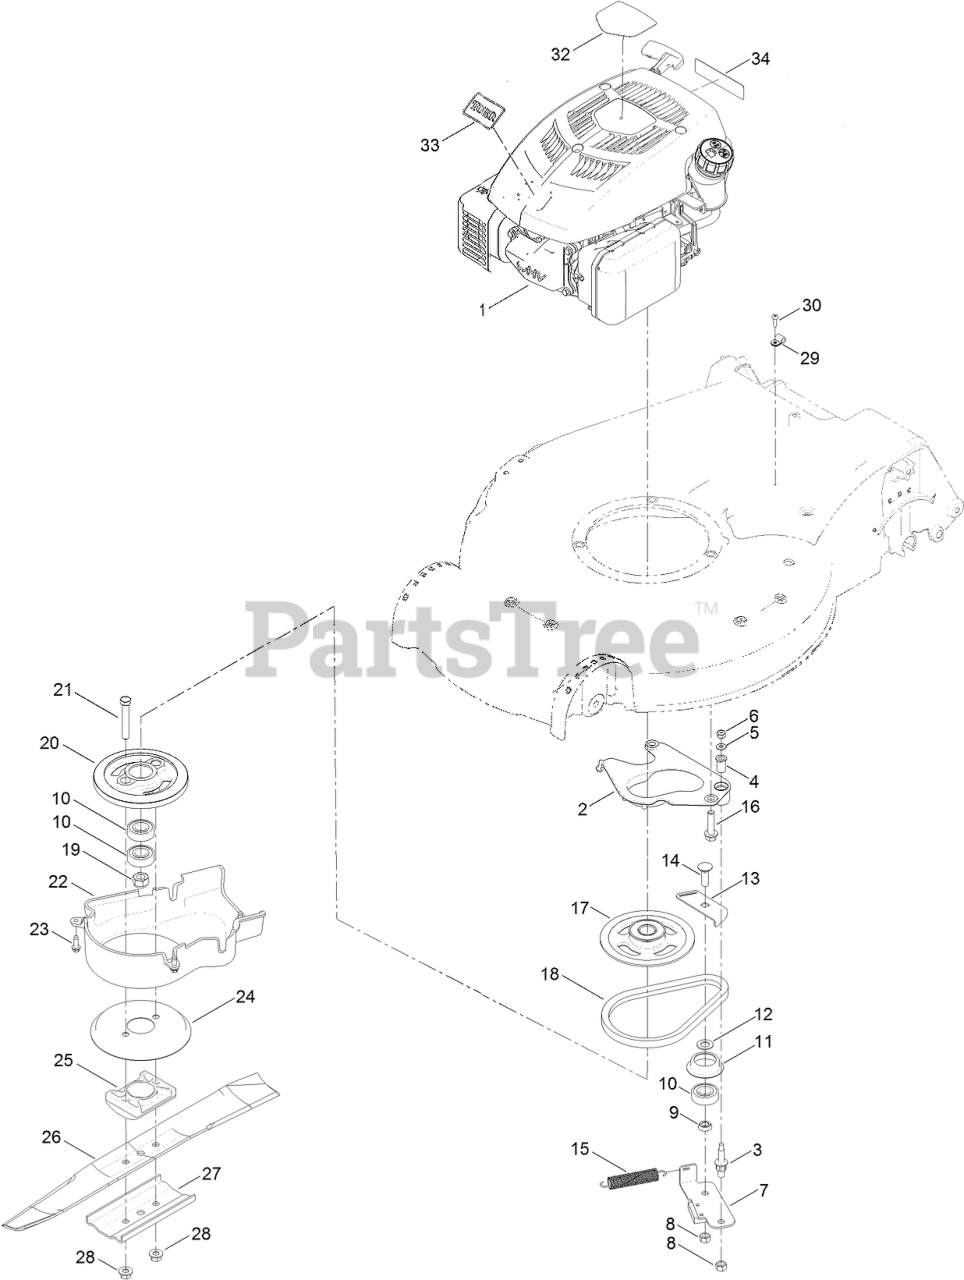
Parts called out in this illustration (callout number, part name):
1	ENGINE-1P65F-2
2	PLATE-ANCHOR
3	BOLT-SHOULDER
4	BUSHING
5	WASHER-FLAT
6	NUT-LOCK, NI
7	PLATE-BRAKE
8	NUT-HEX
9	SPACER-BEARING
10	BEARING-BALL
11	RETAINER-BELT
12	SPACER
13	PLATE-GUIDE
14	BOLT-CARR
15	SPRING-TENSION, BRAKE
16	SCREW-HWH
17	PULLEY
18	BELT
19	NUT-HEX
21	SCREW-HH
23	SCREW-HWHTF
24	DISC
25	SUPPORT-BLADE
27	SUPPORT-BLADE
28	NUT-FLANGE, LOCK
29	CLAMP
32	DECAL-SHROUD
34	DECAL-ARRESTER, SPARK
